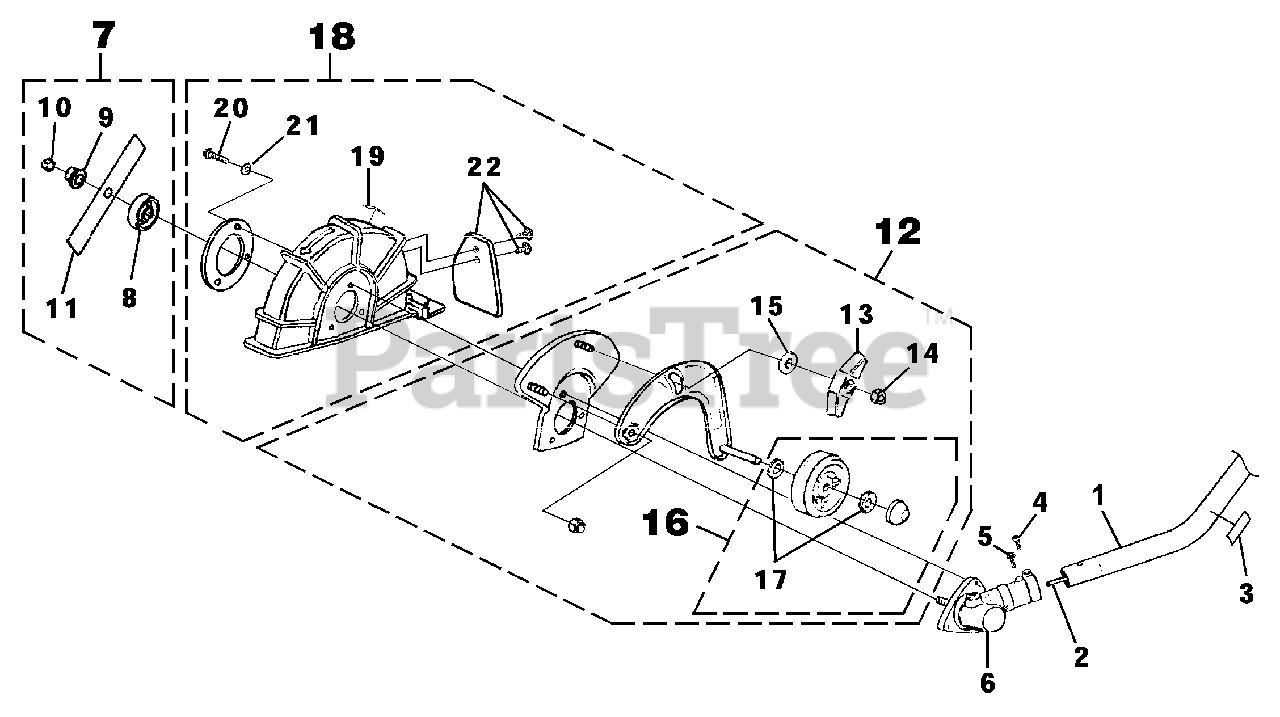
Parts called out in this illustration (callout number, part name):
1	DRIVESHAFT HOUSING
2	SHAFT-Flexible
3	DECAL-Warning
4	SCREW-Cap Socket Hd. (1/4-20 X 7/8")
5	SCREW-Sems Hex Hd. (10-24 X 1/2")
6	GEAR HEAD
7	BLADE KIT
8	WASHER-Flanged
9	WASHER-Flanged (Lower)
10	NUT-Lock
11	BLADE (2" X 9") (Qty.-2)
12	SUPPORT ARM ASSEMBLY
13	KNOB-Adjusting
14	NUT-Hex
15	WASHER-Flat
16	WHEEL KIT
17	WASHER-Flat
18	GUARD KIT
19	DECAL-Warning
20	SCREW-Hex Hd. (10-24 X 5/8")
21	WASHER-Lock (#10)
22	FLAP KIT
